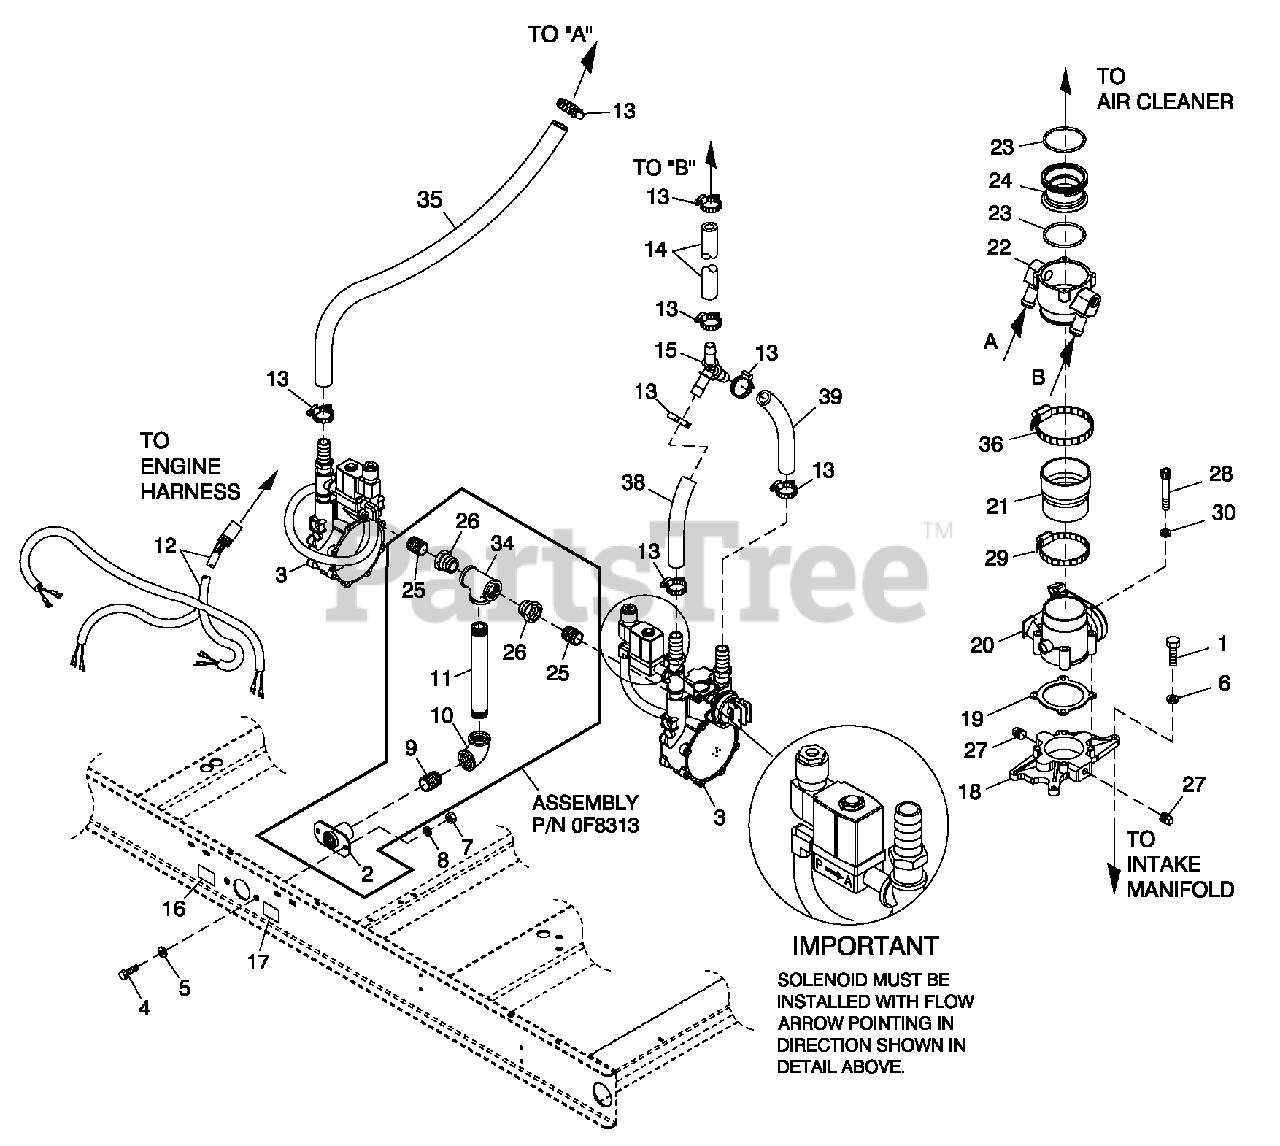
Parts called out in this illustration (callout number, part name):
1	SCREW HHC 5/16-18 X 1-1/4 G5
2	SUPPORT NAT GAS SOLENOID
3	REG ASSY 5.4L 80 KW NG 2009CPL
4	SCREW HHC M12-1.75 X 20 G8.8
5	WASHER FLAT 1/2 ZINC
6	WASHER LOC K M8-5/16
7	NUT HEX M12-1.75 G8 YEL CHR
8	WASHER LOC K1/2
9	NIPPLE CLOSE 1.25 NPT X 1.625
10	ELBOW 90D1-1/4 NPT
11	NIPPLE PIPE 1-1/4 NPT X 3 (100 KW)
12	HARN FUEL JUMPER DUAL REG
13	CLAMP HOSE #8.53-1.00
14	HOSE 3/4 ID SAE-30R2 (42" LG)
15	Y CONNECTOR 500 SERIES BARBS
16	DECAL INLET PRESSURE
17	DECAL FUEL INLET NG
18	MACHINING, INTAKE ADAPTOR 60MM
19	GAS KET GOVERNOR ACTUATOR
20	ACTUATOR BOSCH 60 GOVERNOR
21	REDUCER 3.0" TO 2.75" TURBO
22	MIXER 40/60MM ACTUATOR ASSY
23	O-RING 2-3/4X3/32X2-15/16
24	VENTURI, THROTTLE 38MM
25	NIPPLE CLOSE 3/4X1.375
26	BSHGRDCR HEX1-1/4-3/4
27	PLUG STD PIPE 1/4 STEEL SQ HD
28	SCREW SHC M6-1.0X 50 C8.8
29	CLAMP HOSE #44 2.31-3.25
30	WASHER LOC K M6-1/4
31	HOSE 3/4 ID SAE-30R2 (12" LG)
32	HOSE 3/4 ID SAE-30R2 (9.5" LG)
33	CLAMP HOSE #52 2.81-3.75
34	PIPE TEE 1-1/4 NPT
35	HOSE 3/4 ID SAE-30R2 (45" LG)
